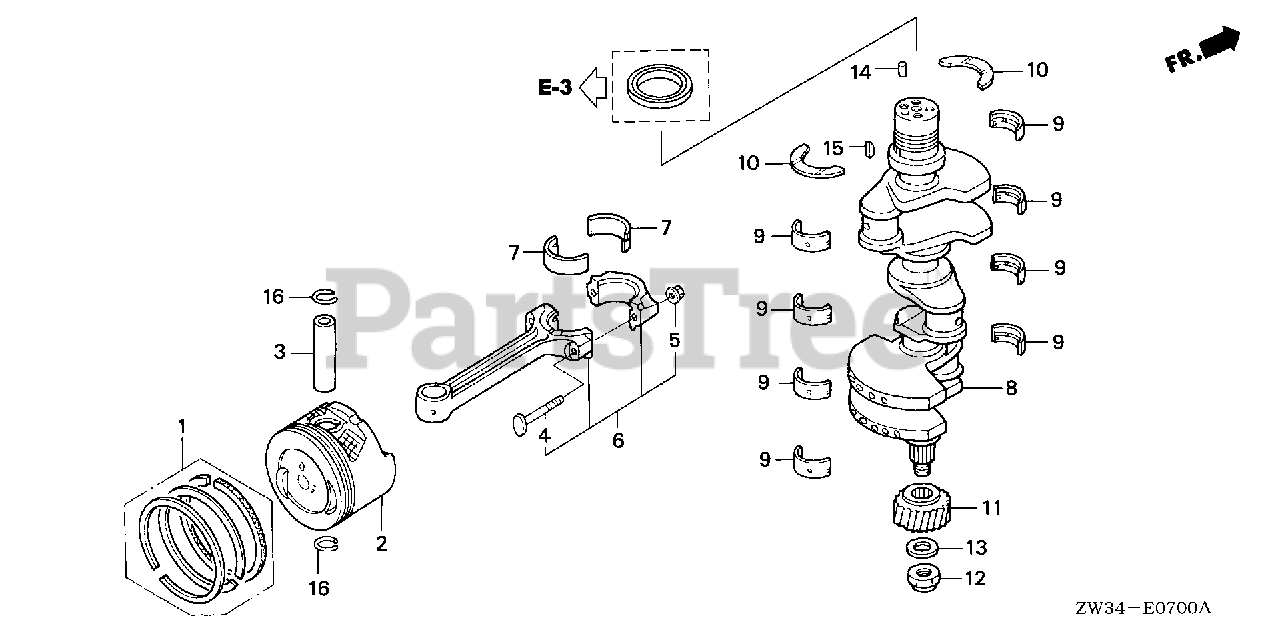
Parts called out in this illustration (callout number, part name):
1	RING SET, PISTON (STD)
1	RING SET, PISTON (0.25)
2	PISTON (STD)
2	PISTON (0.25)
3	PIN, PISTON
4	BOLT, CONNECTING ROD
5	NUT, CONNECTING ROD
6	ROD SET, CONNECTING
7	BEARING A, CONNECTING ROD (BLUE) (DAIDO)
7	BEARING B, CONNECTING ROD (BLACK) (DAIDO)
7	BEARING C, CONNECTING ROD (BROWN) (DAIDO)
7	BEARING D, CONNECTING ROD (GREEN) (DAIDO)
7	BEARING E, CONNECTING ROD (YELLOW) (DAIDO)
7	BEARING F, CONNECTING ROD (PINK) (DAIDO)
7	BEARING G, CONNECTING ROD (RED) (DAIDO)
8	CRANKSHAFT
9	BEARING A, MAIN (BLUE) (DAIDO)
9	BEARING B, MAIN (BLACK) (DAIDO)
9	BEARING C, MAIN (BROWN) (DAIDO)
9	BEARING D, MAIN (GREEN) (DAIDO)
9	BEARING E, MAIN (YELLOW) (DAIDO)
9	BEARING F, MAIN (PINK) (DAIDO)
9	BEARING G, MAIN (RED) (DAIDO)
10	WASHER, THRUST
11	GEAR A, PRIMARY DRIVE (26T) (WHITE)
11	GEAR B, PRIMARY DRIVE (26T) (BLUE)
11	GEAR C, PRIMARY DRIVE (26T) (YELLOW)
12	NUT, FLANGE (22MM)
13	WASHER (22MM)
14	PIN, DOWEL (6X10)
15	KEY, WOODRUFF (25X14)
16	CLIP, PISTON PIN (18MM)
